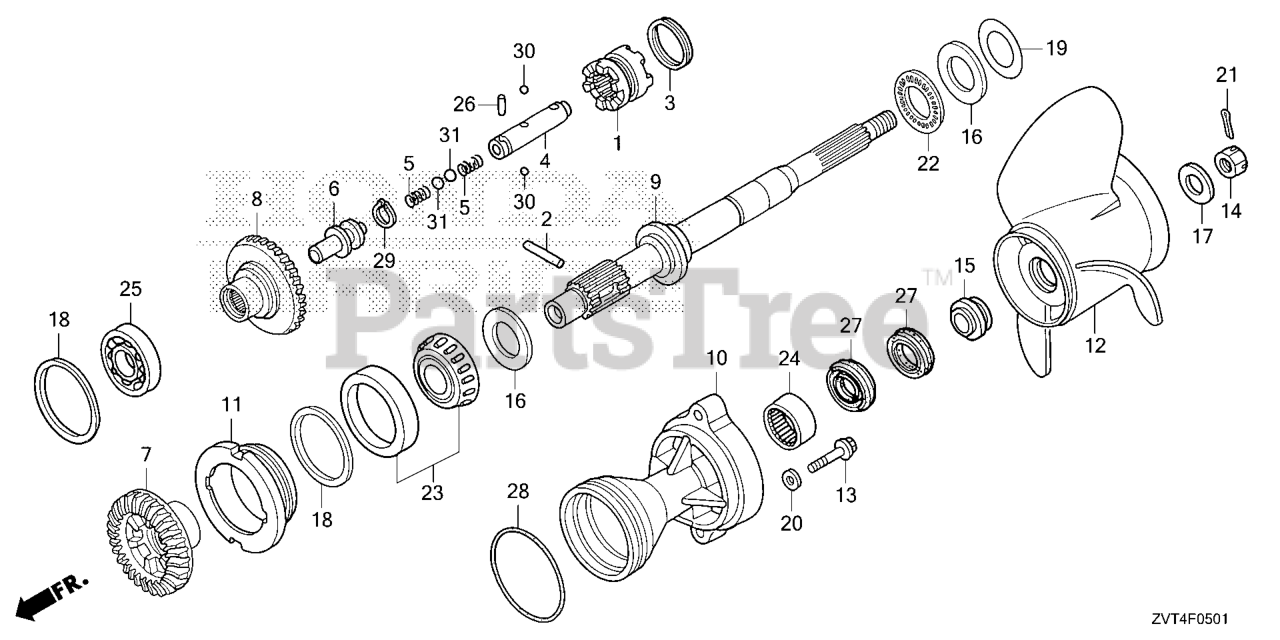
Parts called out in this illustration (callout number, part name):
1	SHIFTER, CLUTCH
2	PIN, SHIFTER (8X47)
3	RING, CROSS PIN
4	SLIDER, SHIFT
5	SPRING, SHIFT
6	PLATE, SHIFT
7	GEAR, BEVEL F
8	GEAR, BEVEL (RVS. 30T) (COUNTER ROTATION)
9	SHAFT, PROPELLER (COUNTER ROTATION)
10	HOLDER, PROPELLER SHAFT *NHB14M* (AQUA MARINE SILVER METALLIC)
10	HOLDER,PROP*NH565*
11	HOLDER, BEARING (COUNTER ROTATION)
12	PROPELLER, THREE-BLADE (14-1/2X15) (C/R)
12	PROPELLER, THREE-BLADE (14-1/4X17) (C/R)
12	PROPELLER, THREE-BLADE (14X19) (C/R)
12	PROPELLER, THREE-BLADE (14X21) (C/R)
12	PROPELLER, THREE-BLADE (14-1/2X23) (C/R)
13	BOLT, FLANGE (10X40)
14	NUT, CASTLE (18MM)
15	WASHER, PROPELLER THRUST
16	WASHER, THRUST BEARING
17	WASHER, PROPELLER
18	SHIM A, BEVEL (0.10)
18	SHIM B, BEVEL (0.15)
18	SHIM C, BEVEL (0.30)
18	SHIM D, BEVEL (0.50)
19	SHIM A, THRUST (0.10)
19	SHIM B, THRUST (0.15)
19	SHIM C, THRUST (0.30)
19	SHIM D, THRUST (0.50)
20	WASHER, PLAIN (10MM)
21	PIN, SPLIT (4.0)
22	BEARING, THRUST (F)
23	BEARING, TAPER (50X90X28)
24	BEARING (30X37X26)
25	BEARING, RADIAL BALL (50X90X20)
26	ROLLER (3X12.8)
27	SEAL, WATER (30X45X7)
28	O-RING (105X3.1)
29	CIRCLIP (OUTER) (14MM)
30	BALL, STEEL (#7) (7/32)
31	BALL, STEEL (#9) (9/32)
